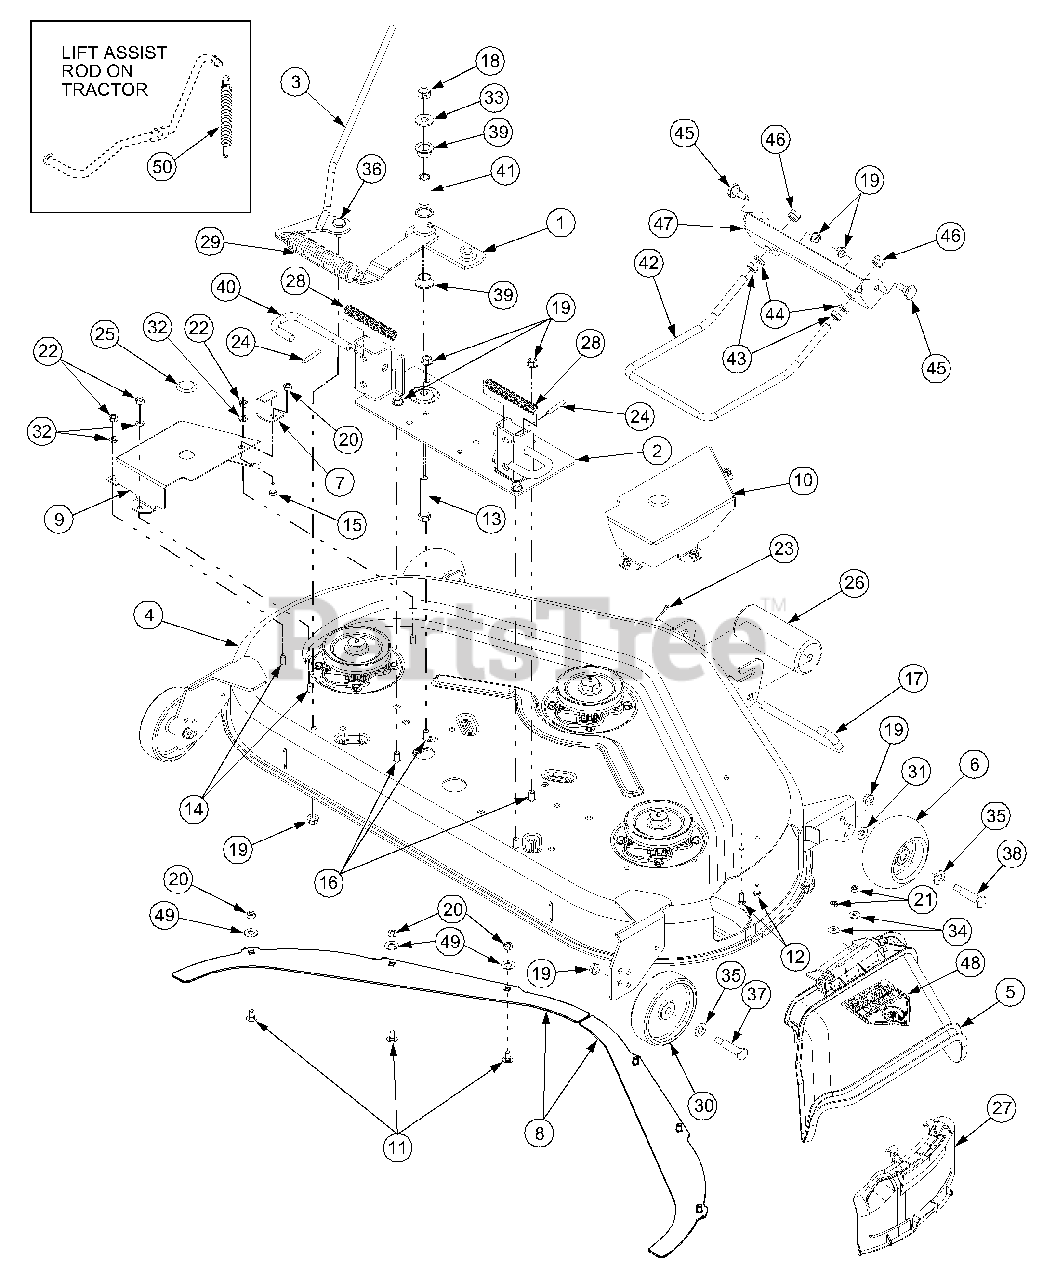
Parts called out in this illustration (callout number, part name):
1	Idler Assembly
2	Plate Assy, Mounting
3	Handle, Tension
4	Deck Housing Assembly
5	Chute Assembly, Discharge
6	Wheel, Deck, w/Fitting
7	Bracket, Stop
8	Baffle, Skirt
9	Belt Cover, LH
10	Belt Cover, RH
11	Bolt, Carriage, 5/16-18 x .62
12	Screw, Hex Cap, 1/4-20 x .62
13	Screw, Hex Cap, 1/2-20 x 3.0
14	Screw, Self Tap, 5/16-18 x .75
15	Screw, Hex Cap, 5/16-18 x .75
16	Bolt, Carriage, 3/8-16 x .75 GR5
17	Pin, Roller, 1/2 Dia x 7.31
18	Nut, Hex Lock, 1/2-20
19	Nut, Flange Lock, 3/8-16
20	Nut, Flange Lock, 5/16-18
21	Nut, Hex, 1/4-20 GR5
22	Nut, Hex, 5/16-18, GR5
23	Pin, Cotter, 1/8 Dia x 1
24	Pin, Spiral Spring, 3/16 Dia x .75
25	Button Plug
26	Front Roller
27	Plug, Mulch
28	Spring, Comp, .66 OD x 1.8
29	Spring, Ext, .162 Dia x 1.25 OD
30	Wheel, Deck, 5.0 x 1.38
31	Washer, Bell. .401 x .870 x .063
32	Washer, Lock, 5/16
33	Washer, Flat, 1/2 x 1.25 x .10
34	Washer, Bell, .265 x .75 x .062
35	Washer, Flat, .510 x 1 x .060
36	Bolt, Shoulder, .498 Dia x .340
37	Screw, Shoulder, .498 x 1.635
38	Bolt, Shoulder
39	Bearing, Flange, 3/4 ID x .52 LG
40	Pin, Mower Support
41	Spacer, .5 OD x .75 x 2.07 Lg
42	Rod, Front Lift
43	Nut, Hex Jam, 1/2-13 GR5
44	Washer, Lock, 1/2
45	Bolt, Shoulder, .50 Dia. x .494 Lg
46	Nut, Hex Insert Lock, 1/2-13
47	Bracket, Front Lift
48	Graphic, Danger
49	Washer, Flat, .474 x .88 x .064
50	Spring, Ext., .91" OD x 7.33
